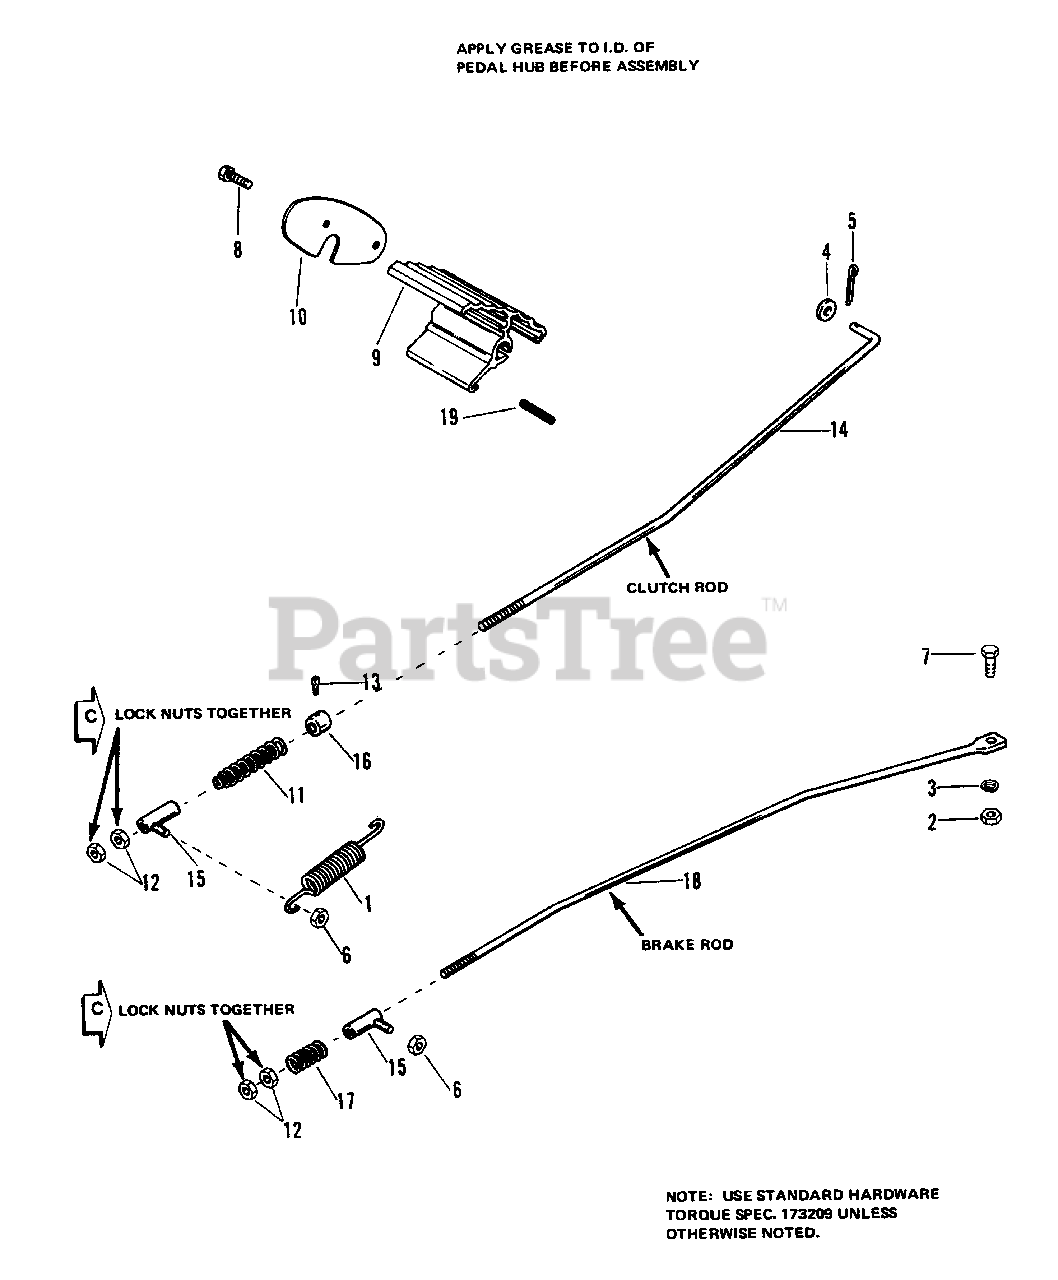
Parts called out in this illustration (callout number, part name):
1	SPRING, Return
2	NUT, Hex 1/4-20
3	LOCKWASHER, Spring 1/4
4	WASHER, Plain 1/4
5	PlN, Cotter 3/32 x 3/4
6	LOCKNUT Hex 5/16-18
7	CAPSCREW, Hex Hd., 1/4-20 x 3/4
8	SCREW, Hex Washer Hd. 1/4-20 x 5/8
9	PEDAL, Foot
10	PLATE, End
11	SPRING, Compression
12	NUT, Hex, 5/16-18
13	SCREW, Set Sq Hd Cup., 1/4-20 x 3/8
14	ROD, Clutch
15	GUIDE ASSY, Rod
16	COLLAR, Set
18	ROD, Brake
